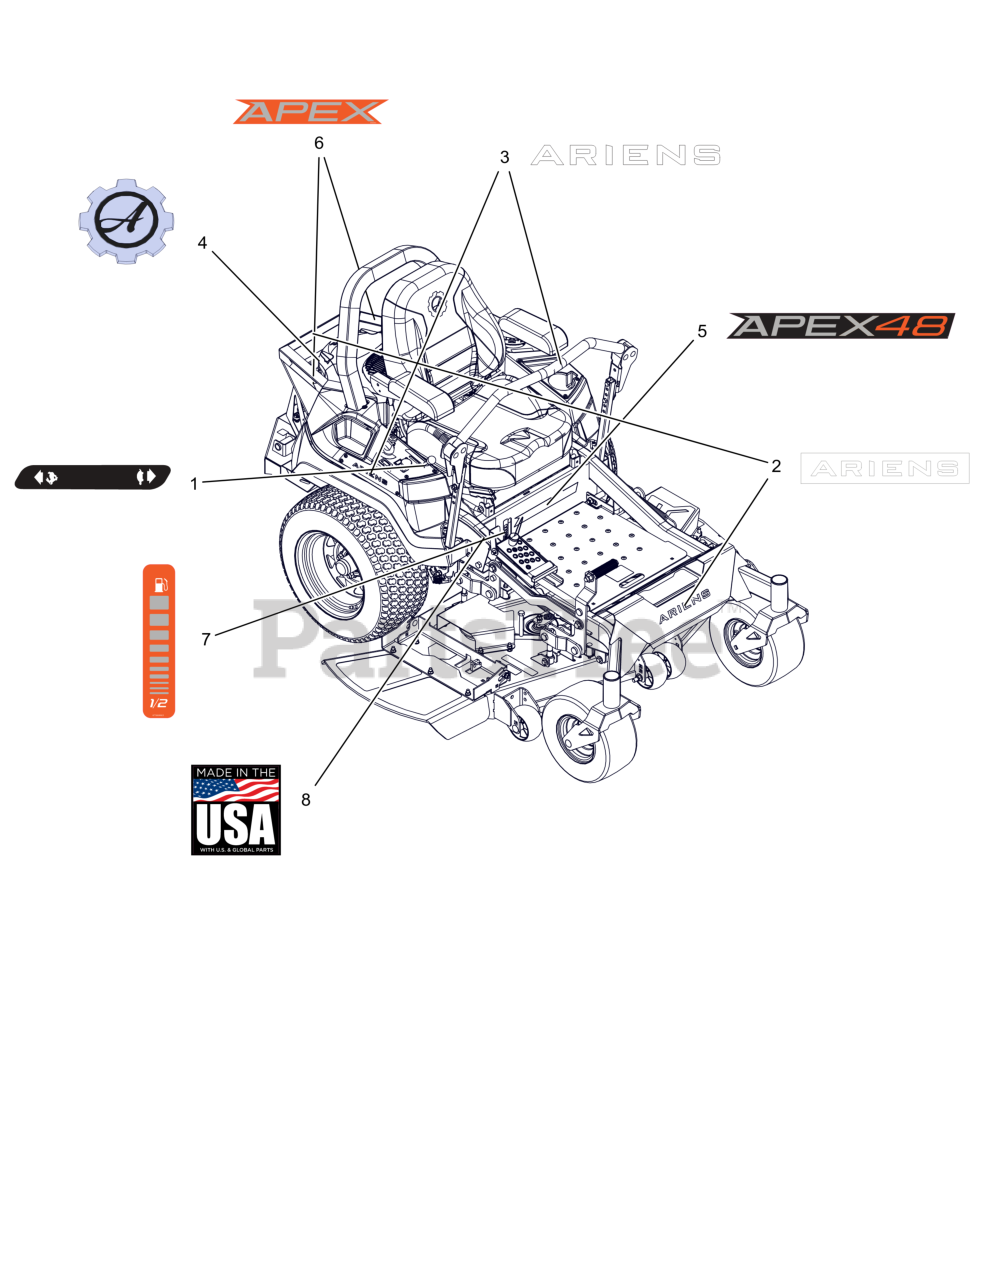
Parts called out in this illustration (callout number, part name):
1	DECAL, DASH DECAL
2	DECAL - ARIENS 9.625"
3	DECAL, ARIENS (6.50")
4	DECAL, ARIENS-GEAR BADGE -THK
5	DECAL, 48" APEX KICKPLATE
6	DECAL, APEX FENDER
7	DECAL, ARIENS FUEL LEVEL
8	DECAL, MADE IN USA
